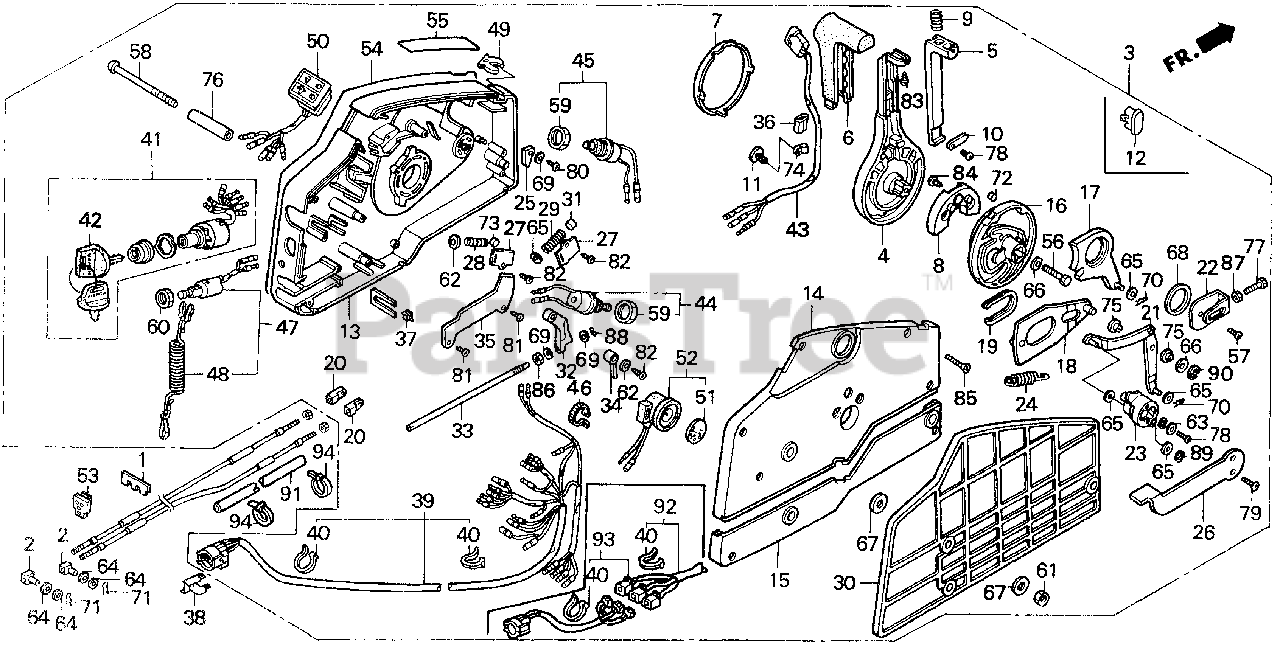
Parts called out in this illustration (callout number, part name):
1	PLATE, REMOTE CONTROL CABLE
2	PIVOT, SHIFT
3	BOX ASSY., REMOTE CONTROL (P/T)
3	BOX ASSY., REMOTE CONTROL
3	BOX, MOUNT CONTROL
4	HANDLE, REMOTE CONTROL
5	LEVER, HANDLE LOCK
6	GRIP, REMOTE CONTROL HANDLE
7	CAP, HANDLE
8	BLOCK, NEUTRAL LOCK
9	SPRING, REMOTE CONTROL HANDLE
10	PLATE, LEVER SETTING
11	CLAMP, HARNESS
13	HOUSING, REMOTE CONTROL BOX (A)
14	HOUSING, REMOTE CONTROL BOX (B)
15	HOUSING, REMOTE CONTROL BOX (C)
16	WHEEL, CONTROL
17	ARM, SHIFT LINK
18	PLATE, SLIDING
19	COLLAR, SLIDING PLATE
20	PIVOT, SHIFT
21	ARM, LINK JOINT
22	BRACKET, LINK JOINT
23	WHEEL, ACCELERATOR
24	SPRING, ACCELERATOR WHEEL
25	CAM, STARTER SWITCH
26	LEVER, IDLE
27	PLATE, SPRING SETTING
28	SPRING, SHIFT CLICK
29	SPRING, CHOKE RETURN
30	SPACER, REMOTE CONTROL BOX
31	SPACER, CLICK SPRING
32	BLOCK, THROTTLE FRICTION
33	BOLT, FRICTION
34	SPACER, NEUTRAL SWITCH
35	CLAMP, POWER TILT CORD
36	PIPE, HARNESS GUIDE
37	SPACER, CABLE CLAMP
38	BRACKET, CONNECTOR
40	TIE, CABLE
41	SWITCH ASSY., COMBINATION
42	KEY ASSY., COMBINATION SWITCH
43	SWITCH ASSY., POWER TRIM-TILT
44	SWITCH ASSY., THROTTLE
45	SWITCH ASSY., SOLENOID
47	SWITCH ASSY., EMERGENCY STOP
48	WIRE, EMERGENCY
49	CLIP, EMERGENCY LOCK
50	LAMP ASSY., INDICATOR
51	PLATE, TURN SIGNAL BUZZER
52	BUZZER, WARNING
53	GROMMET, CASE (LOWER) (A)
54	PLATE, REMOTE CONTROL
55	MARK, FAST IDLE
56	BOLT, HEX. (8X35)
57	SCREW, PAN (6X10)
58	SCREW (6X95)
59	NUT, HEX. (20MM)
60	NUT, HEX. (16MM)
61	NUT, HEX. (6MM)
63	WASHER, PLAIN (5MM)
64	WASHER, PLAIN (6MM)
65	WASHER, PLAIN (6MM)
66	WASHER, PLAIN (8MM)
67	WASHER (6MM)
68	WASHER (28MM)
69	WASHER, PLAIN (4MM)
70	PIN, LOCK (6MM)
71	PIN, SPECIAL LOCK (6MM)
73	ROLLER, CLICK
74	CLIP, WIRE HARNESS
75	COLLAR, LINK JOINT
76	COLLAR, DISTANCE (6X10X43.5)
77	BOLT, HEX. (5X16)
78	SCREW, PAN (5X10)
79	SCREW, OVAL (5X12)
80	SCREW, TAPPING (4X10)
81	SCREW, TAPPING (5X8)
82	SCREW, TAPPING (5X10)
83	SCREW, TAPPING (5X12)
84	SCREW, TAPPING (6X16)
85	SCREW, TAPPING (5X25)
86	NUT, HEX. (6MM)
87	NUT, HEX. (5MM)
88	E-RING (3MM)
89	E-RING (4MM)
90	E-RING (7MM)
91	TUBE, CORRUGATED (28MM)
92	CABLE ASSY., REMOTE CONTROL (B)
93	CABLE (14WIRE) (16.5')
94	BAND, SELF-LOCK
